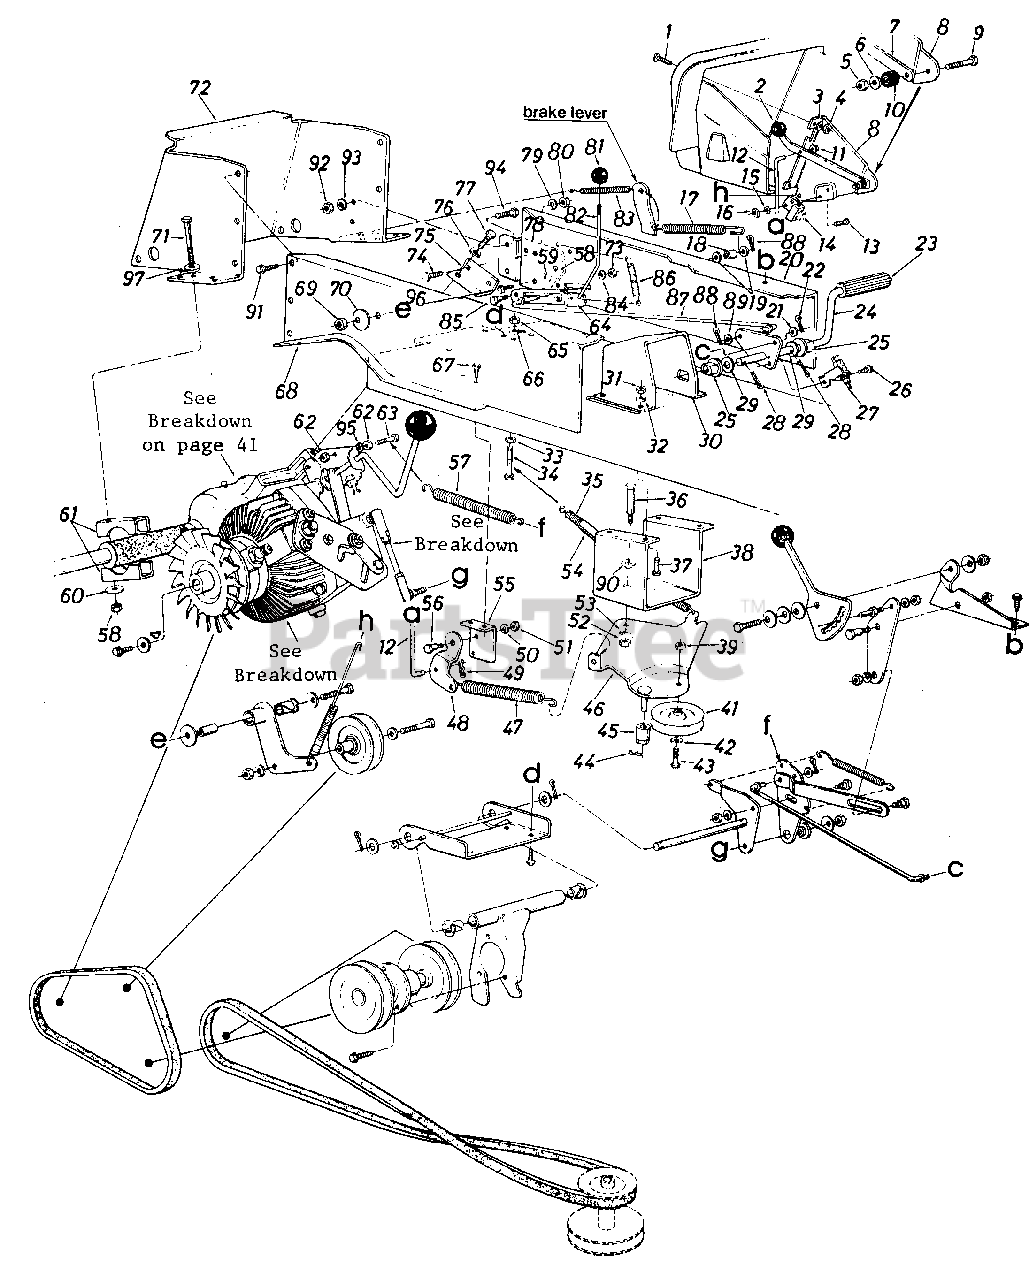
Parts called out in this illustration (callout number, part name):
1	Truss Mach. Scr. 1/4-20 x .50" Lg.
2	Knob Blade Clutch
4	Hex Sems Nut 1/4-20 Thd.
5	Hex Cent. L-Nut 1/4-20 Thd.
6	Fl-Wash. 1/4" I.D. x .75" O.D.
7	PTO Lever
8	Deck Clutch Control Brkt.
9	Hex Bolt 1/4-20 x .75" Lg.*
10	Rubber Wash. .33" I.D. x .87" O.D.
11	Push Cap 1/4" Rod
12	Deck Control Rod
13	Truss Mach. Scr. #10-24 x .50" Lg.*
14	Safety Switch
15	Ext. L-Wash. #10 Scr.
16	Hex Nut #10-24 Thd.*
17	Extension Spring .75" O.Dx 5.56" Lg.
18	Spacer.375" I.D. x .625" O.D. x .445 " Lg. .
19	Fl-Wash. .385" I.D. x .87" O.D.
20	Side Panel Upper Frame L. H .
21	Fl-Wash. .385" I.D. x .87" O.D.
22	Cotter Pin 3/32" Dia. x .75" Lg.*
23	Foot Pad
24	Foot Pedal Brkt. Ass'y
25	Flange Brg. .630" I.D. x 1.25" O.D.
26	Hex Wash. Hd. S-Tap Scr1/4-20 x .50" Lg.
27	Safety Switch
28	Cotter Pin 1/8" Dia. x 1.00" Lg.
29	Fl-Wash. .640" I.D. x .24" O.D.
30	Steering Gear Support Ass'y.
31	Fl-Wash. .385" I.D. x .87" O.D.
32	L-Wash. 5/16" I.D.*
33	Hex Nut 1/4-20 Thd.*
34	Hex Bolt 1/4-20 x 2.0" Lg.*
35	Extension Spring .50" O.Dx 6.37" Lg.
36	Shld. Bolt 7/16" Dia. x .16"
37	Hex Bolt 5/16-18 x 1.00"*
38	Idler Mtg. Brkt. Deck
39	Hex L-Nut 3/8-16 Thd.
41	V-ldler Pulley
42	Fl-Wash. 3/8" I.D.
43	Hex Bolt 3/8-16 x 1.75" Lg.*
44	Cotter Pin 5/16" Rod
45	Spacer
46	Idler Brkt. Ass'y.
47	Extension Spring Deck Control
48	Deck Control Pivot Brkt.
49	Cotter Pin 5/16" Rod
50	L-Wash. 5/16" I.D.*
51	Hex Nut 5/16-18 Thd.*
52	Hex Nut 5/16-18 Thd.*
53	L-Wash. 5/16" I.D.*
54	Convoluted Conduit .50" I.D. x 4" Lg.
55	Parking Brake Cam Mtg Brkt.
56	Shld. Bolt 7/16" Dia. x .16" Lg.
57	Extension Spring
58	Hex Nut 3/8-16 Thd.*
59	L-Wash. 3/8" I.D.*
60	Bell-Wash. .39" I.D. x 1.13" O.D.
61	Rear Axle Brkt.
62	Hex Nut 5/16-24 Thd.*
63	Hex Self-Tap Scr. 5/16-24 x 1 .5"
64	Parking Brake Cam
65	Hex Nut 1/4-20 Thd.*
66	L-Wash. 1/4" I.D.*
67	Hex Wash. Hd. S-Tap Scr. 1/4-20 x .50" Lg.
68	Side Panel Upper Frame R.H.
69	Hex Nut 3/8-24 Thd.*
70	Fl-Wash. .39" I.D. x 1.5" O.D.
71	Hex Bolt 3/8-16 x 3.50" Lg.*
72	Hitch Plate
73	Hex Nut 3/8-16 Thd.*
74	Rib Neck Scr. 3/8-24 x 1.0"
75	Mounting Brkt. Transaxle
76	L-Wash. 3/8" I.D.*
77	Hex Bolt 3/8-16 x 1.00" Lg. (Grade 5)
78	Reinforcement Plate Frame
79	L-Wash. 3/8" I.D.*
80	Hex Nut 3/8-24 Thd.*
81	Gear Shift Knob
82	Parking Brake Link
83	Extension Spring .38" O.D, x 3.18" Lg.
84	Hex Nut 3/8-16 Thd.*
85	Shld. Bolt .500" Dia. x .170
86	Extension Spring .38" O.D, x 3.18" Lg.
87	Rod Brake .38" Dia. x 19.3" Lg.
88	Cotter Pin 3/32" Dia. x .75" Lg.
89	Fl-Wash. .385" I.D. x .87" O.D.
90	Wave Wash.
91	Hex AB-Tap Scr. 5/16 x .75" Lg.
92	Hex Nut 5/16-24 Thd.*
93	L-Wash. 5/16" I.D.*
94	Hex Bolt 5/16-24 x .75" Lg.*
95	L-Wash. 5/16" I.D.
96	Hex Bolt 3/8-16 x .75" Lg.*
97	Fl-Wash. .385" I.D. x .87"
